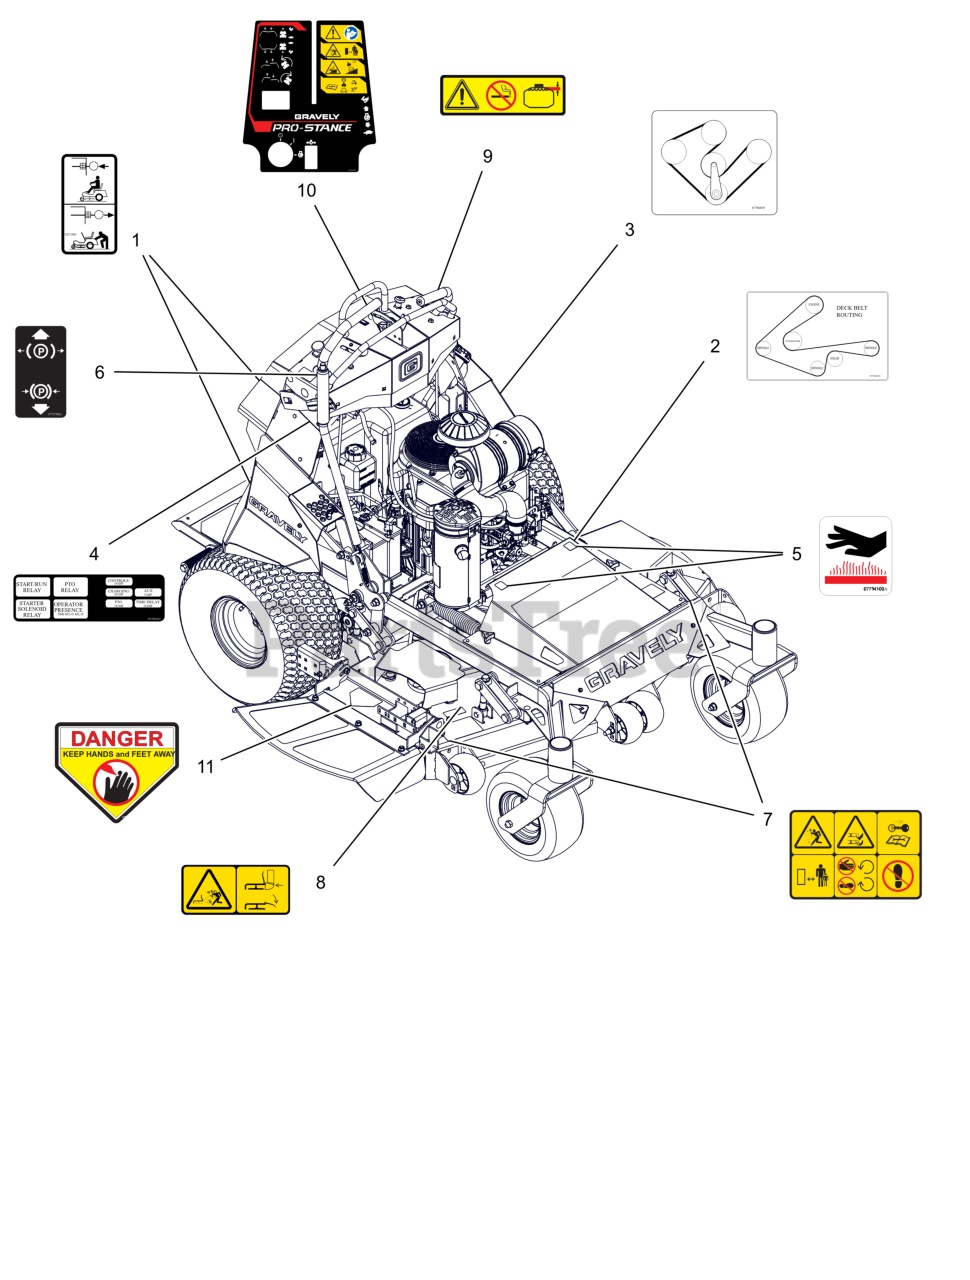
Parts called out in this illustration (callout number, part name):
1	DECAL, TRANSMISSION DISCONNECT
2	DECAL, BELT ROUTING 48/52
3	DECAL, PROSTANCE HYD BELT ROUT
4	DECAL, FUSE BOX
5	DECAL, HOT SURFACE
6	DECAL, PARKING BRAKE LEVER
7	DECAL, SAFETY - MOWER DECK
8	DECAL, SAFETY - DECK GUARDING
9	DECAL, FUEL WARNING
10	DECAL, DASH - PROSTANCE
11	DECAL, DANGER
